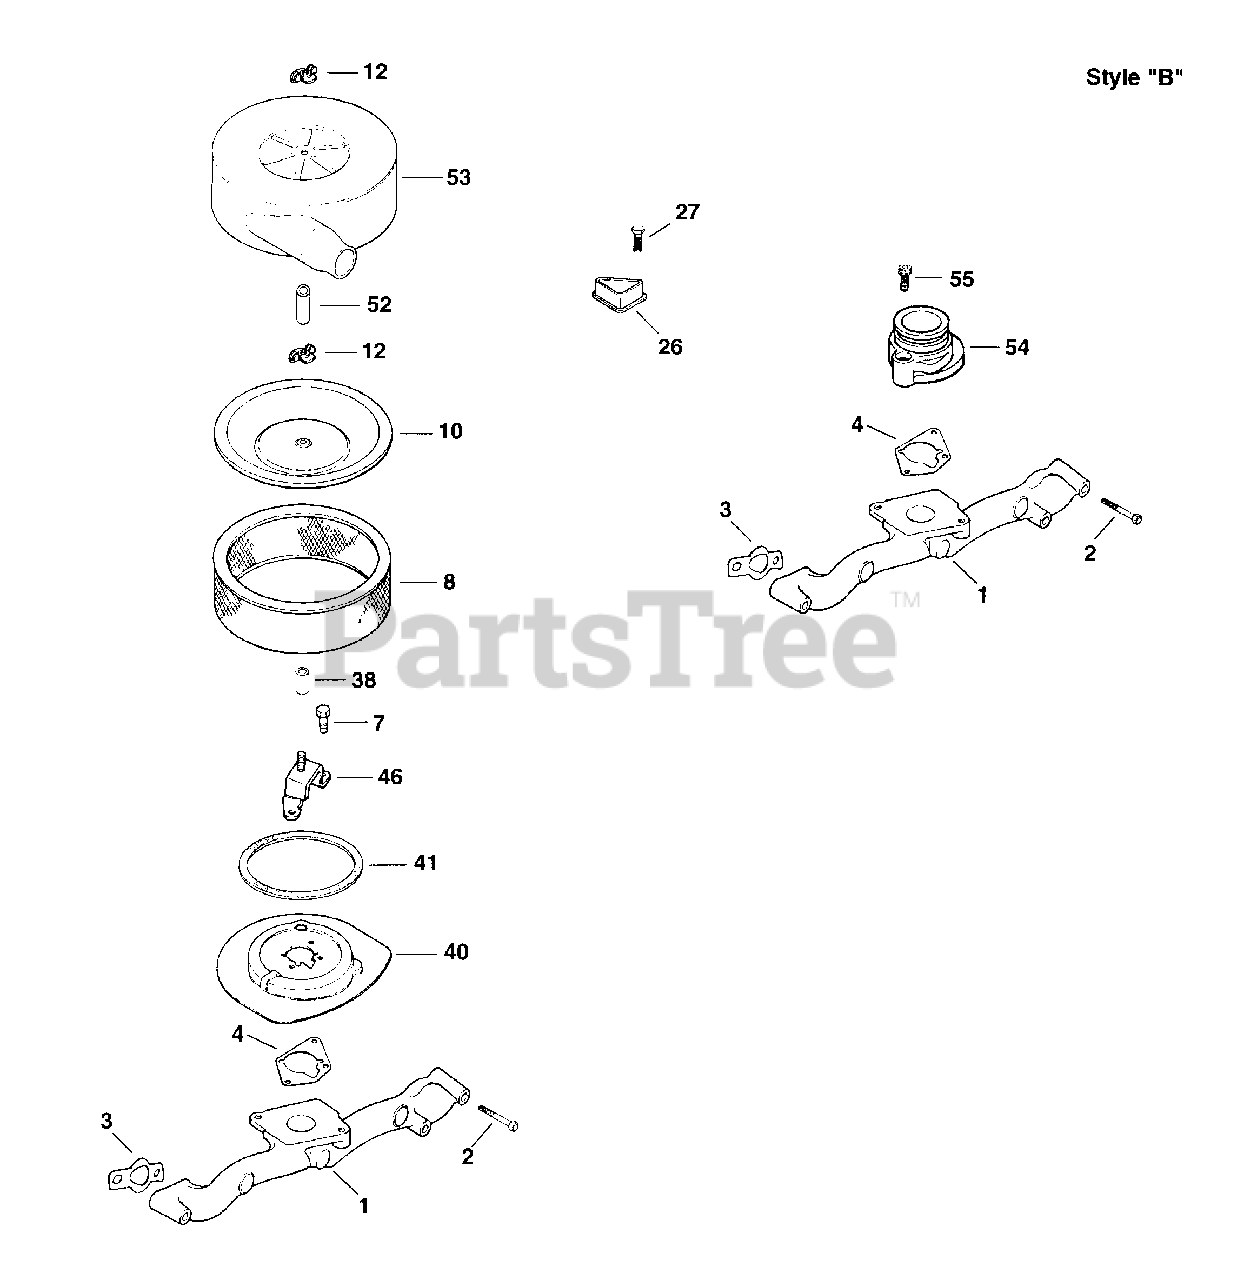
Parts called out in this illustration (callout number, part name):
1	MANIFOLD, METAL INTAKE
2	Screw, hex. flange M6x1.0x55
3	GASKET, INTAKE MANIFOLD USE 24 041 79-S
4	GASKET, AIR CLEANER BASE
7	SCREW - USE M-639016
8	ELEMENT, AIR CLEANER - Also available Retail Packaged 47 883 03-S1 Air Filter Kit
10	COVER, INNER AIR CLEANER
12	NUT, WING
26	COVER, BLOWER HOUSING USE 24 096 160-S
27	SCREW, WSH HD TAP #8-18X1/2" USE 25 086 91-S
38	SEAL, BREATHER
40	BASE, AIR CLEANER-USE 24 094 91-S
41	KIT - USE 24 743 18
